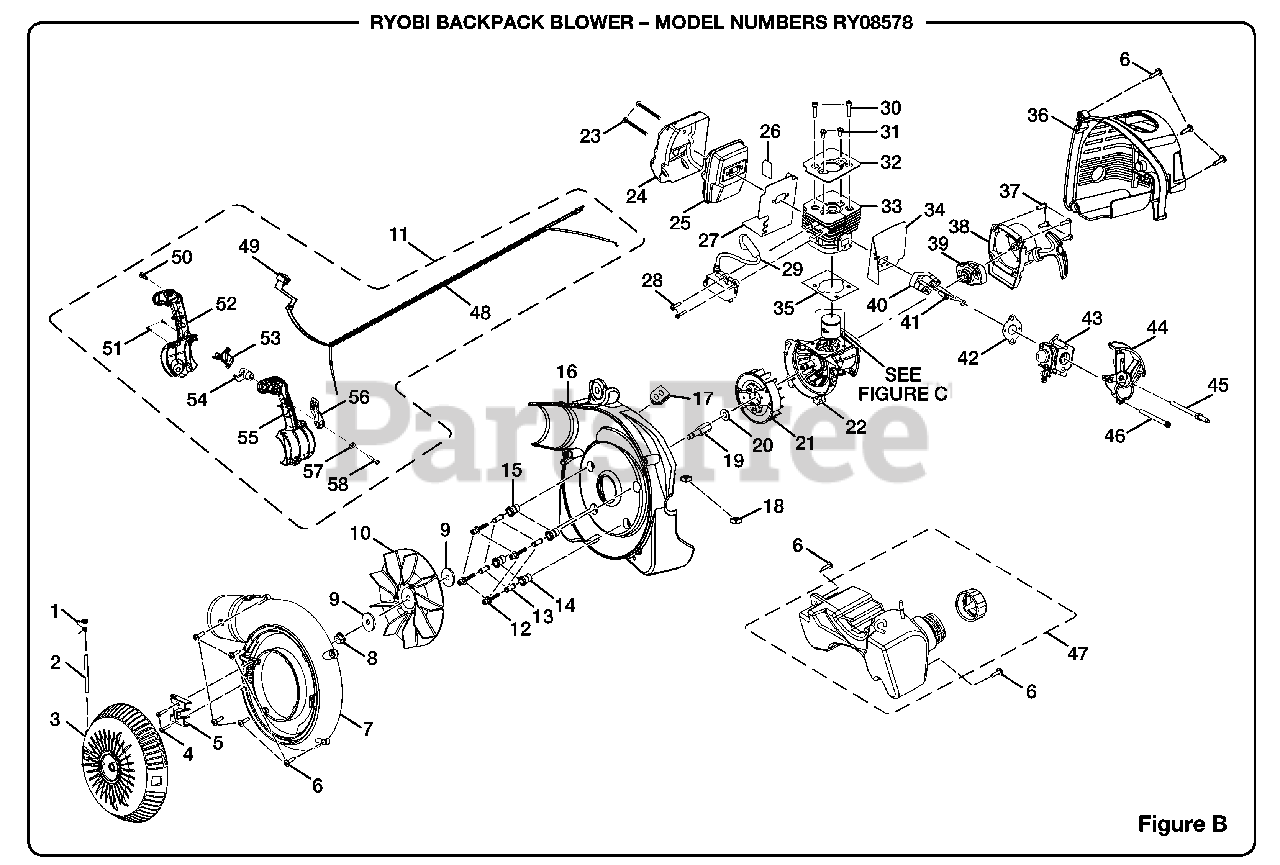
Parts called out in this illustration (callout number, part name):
1	Vacuum Door Hinge Spring
2	Hinge Pin
3	Vacuum Door
4	Screw (M4 X 19 mm)
5	Vacuum Door Hinge
6	Screw
7	Outer Volute Housing
8	Retaining Washer Nut
9	Washer (Fan Spacer)
10	24.5cc Blower Fan
11	Control Assembly
12	Screw (M5 X 8 mm Cap Hd.)
13	Bushing Sleeve
14	Anti Vibration Bushing
15	Vibration Isolator
16	Inner Volute Housing
17	Rubber Grommet
18	Square Nut
19	Crankshaft Extension
20	Washer (2.3 mm)
21	Flywheel Assembly
22	Crankcase Assembly
23	Screw (M5 X 50 mm)
24	Heat Shield
25	Muffler Assembly
26	Heat Shield
27	Gasket Muffler
28	Screw (M4 X 22 mm)
29	Coil & Boot Assembly
30	Screw (M5 X 22 mm)
31	Screw w/Washer (M5 X 10 mm)
32	Plate for Cylinder
33	Cylinder
34	Insulator Gasket
35	Cylinder Gasket
36	Engine Shroud Housing
37	Screw (M5 X 16 mm)
38	Starter Assembly
39	Pulley Assembly
41	Screw w/Washer (M5 X 31 mm)
42	Carburetor Gasket
43	Carburetor
44	Roto-choke base
45	Hex Bolt (Double Side)
46	Screw (M5 X 25 mm)
47	Fuel Tank Assembly
48	Corrugated Tube
50	Screw (10-14 X 3/4 in.)
51	Screw (M4 X 16 mm Pan Head)
52	Housing - RH remote control
54	Trigger Lock
55	Housing - LH remote control
56	Cruise Control Lever
58	Screw (M4 X 25 mm)
